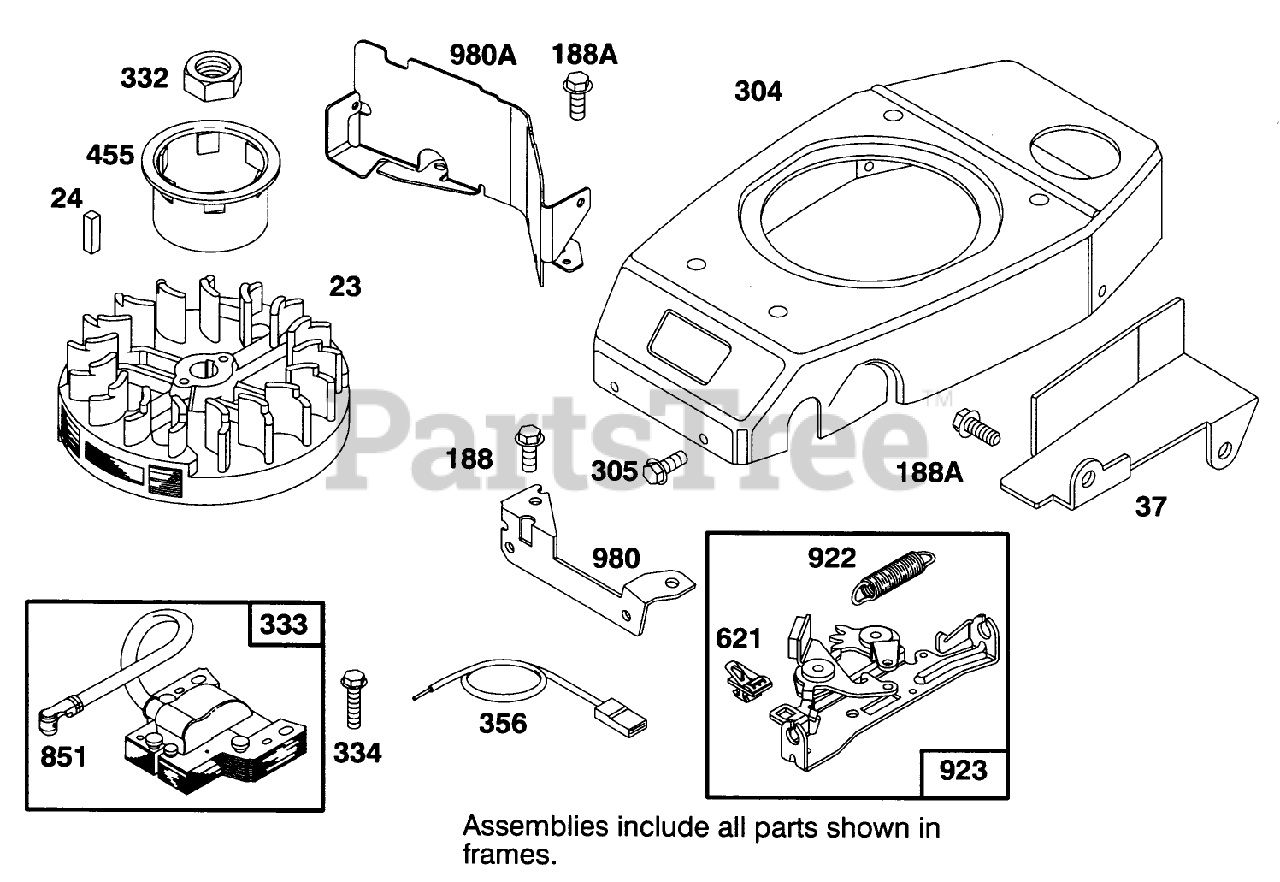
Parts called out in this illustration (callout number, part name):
24	KEY - FLYWHEEL
188A	SCREW - SEM
304	HOUSING - BLOWER
305	SCREW - HEX HEAD
332	NUT - HEXAGON
356	WIRE - GROUND
621	STOP SWITCH
980	BRACKET-BLOWER HSG
980A	BLOWER HSG BRACKET
